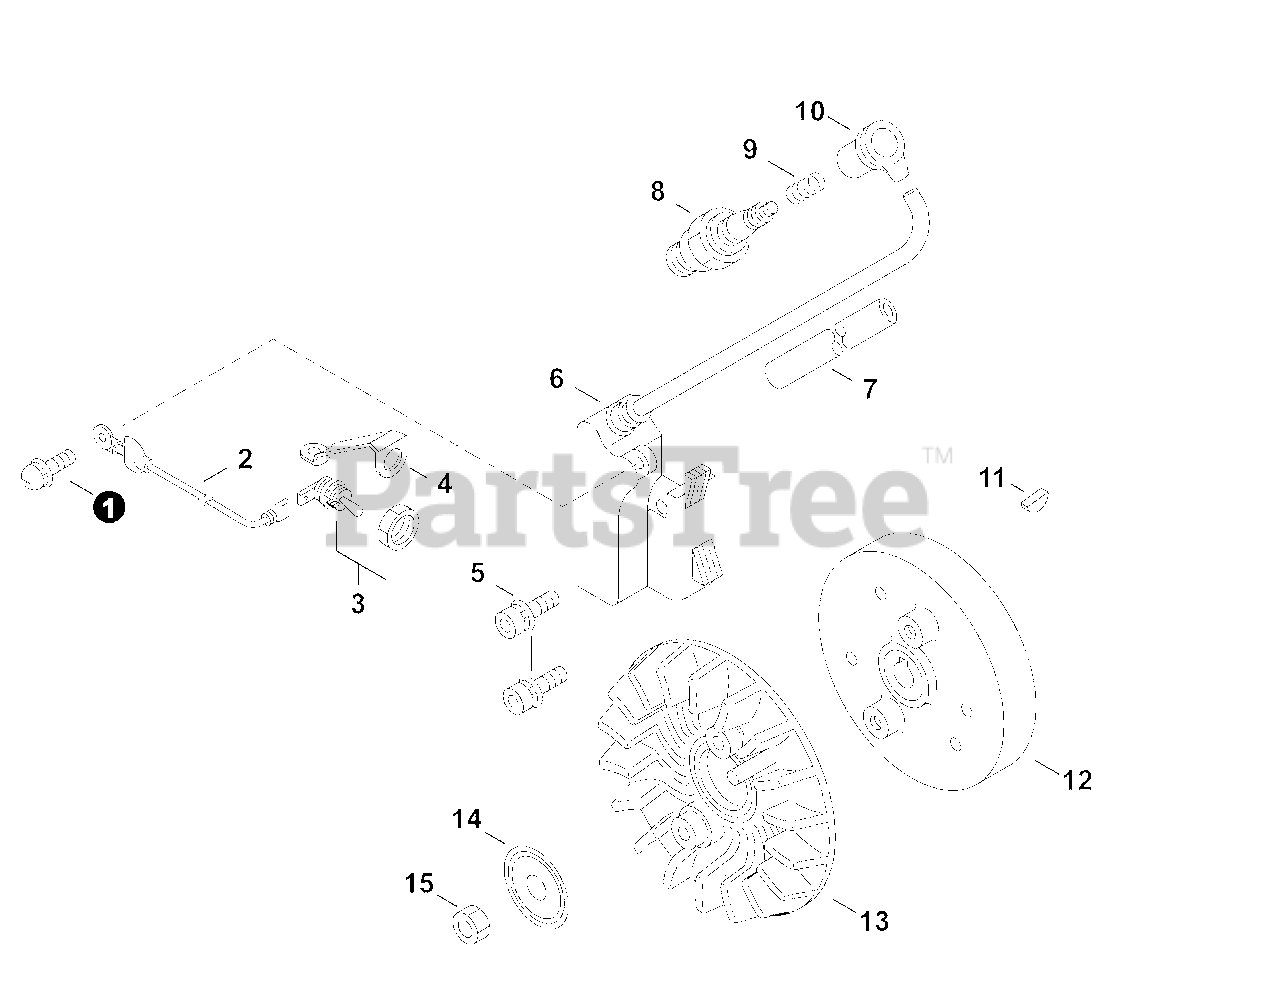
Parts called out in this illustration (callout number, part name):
1	SCREW 4×8
3	SWITCH, ON-OFF
4	PLATE, GROUND
5	BOLT 4×20
6	COIL, IGNITION
8	SPARK PLUG - BPMR7A
9	TERMINAL, SPARK PLUG
10	CAP, SPARK PLUG
11	KEY, WOODRUFF
12	FLYWHEEL
14	WASHER 8.2×31×0.8
